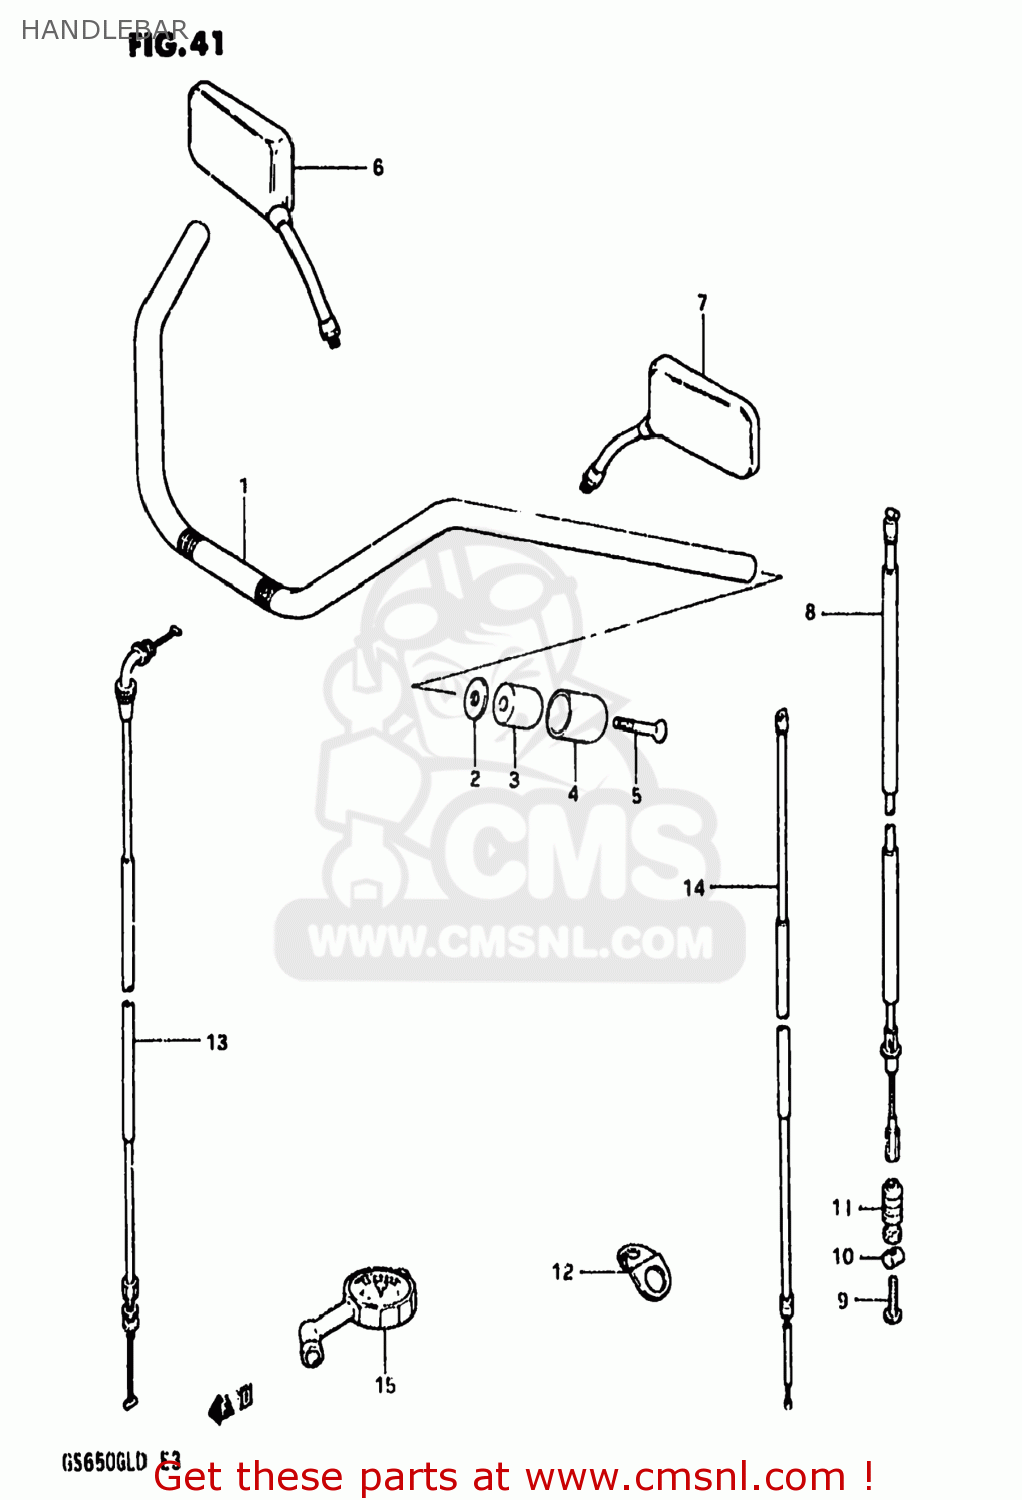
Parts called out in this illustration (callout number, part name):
1	HANDLEBAR
2	SPACER,BALANCER
3	BALANCER,HANDLEBAR
4	CAP,BALANCER
5	SCREW
6	MIRROR ASSEMBLY,REAR VIEW
7	MIRROR ASSEMBLY,REAR VIEW
8	CABLE ASSEMBLY,CLUTCH
9	SCREW
10	PIN
11	DUST SEAL
12	GUIDE,BRAKE HOSE
13	CABLE ASSEMBLY,THROTTLE
14	CABLE COMP,STARTER
15	GAUGE ASSY,AIR PRESSURE
